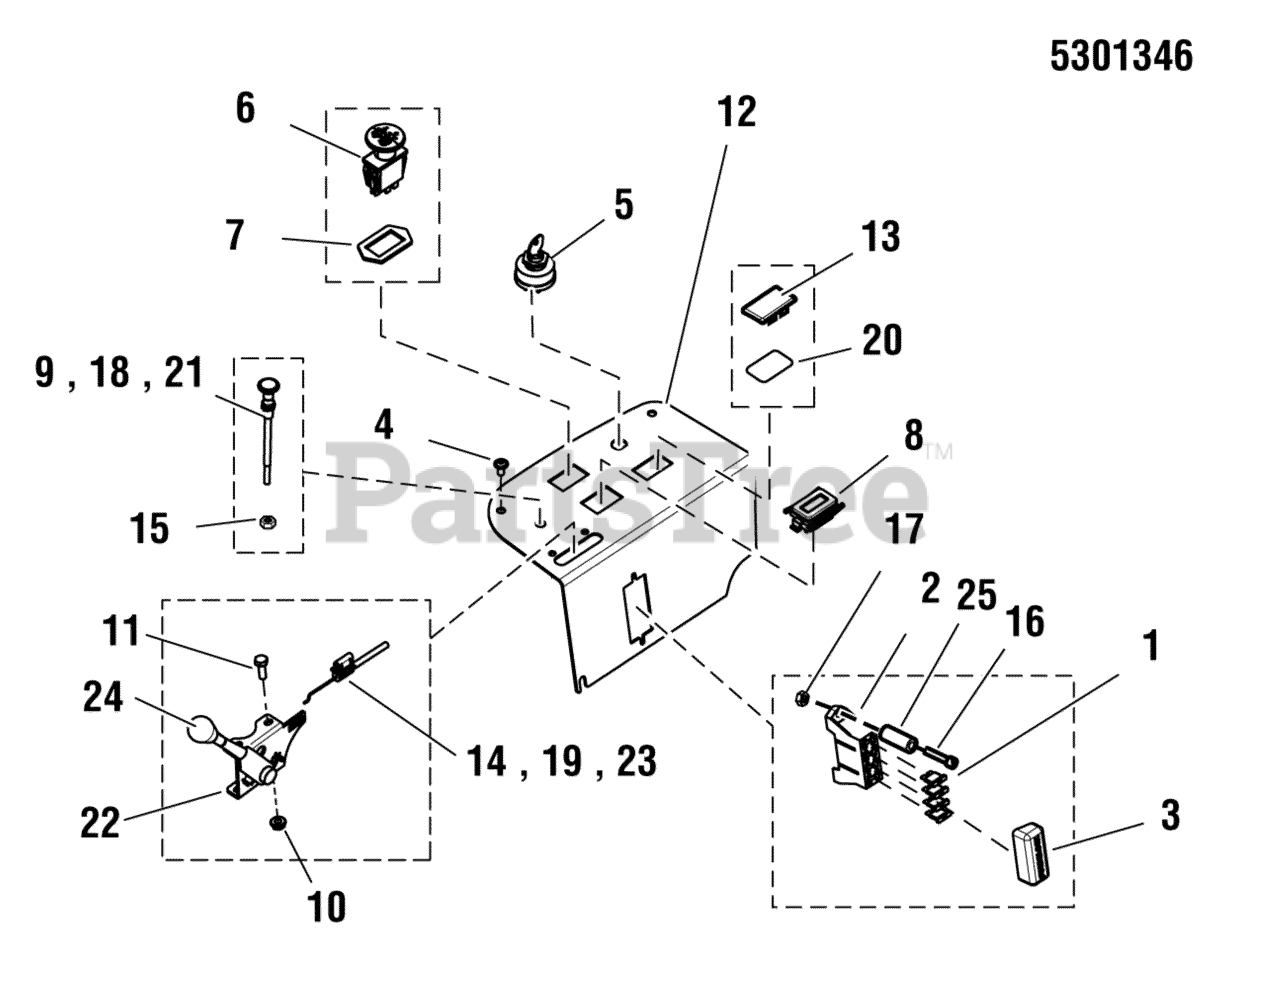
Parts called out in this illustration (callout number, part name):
1	FUSE, ATO-20 (20 AMP)(SV)
2	FUSE, BLOCK (SV)
3	COVER, VINYL, FUSE BLOCK
4	SCREW, ALLEN HEAD 1/4-20X.500 ZINC PHOS
5	SWITCH, IGNITION, 6 POST
6	SWITCH, BLADE ENGAGEMENT
7	RING, SWITCH RETAINER
8	HOUR METER, ASSEMBLE
8	HOUR METER
9	CABLE, Choke Control, 47"
10	NUT, Hex, Nylon Lock, #10-24
11	SCREW, #10-24 X 3/4" ROUND PHILLIPS
12	PANEL, CONTROL
12	PANEL, CONTROL, IS2000Z
13	PLUG, .820X1.44 HOLE, BLACK PLASTIC
14	CABLE, THROTTLE 47"
15	NUT, 3/8-24 HEX (SV)
16	SCREW, #10-24 X 2" ROUND PHILLIPS
17	NUT, Hex, Nylon Lock, #10-24
18	CABLE, CHOKE CONTROL, 56", DETENTED
19	CABLE, THROTTLE, 52"
20	O-RING, 7/8" ID X 1/16" W
21	CABLE, CHOKE CONTROL, 51" (Z)
22	LEVER, THROTTLE CONTROL, HEAVY-DUTY
23	CABLE, THROTTLE, 42"
24	THROTTLE CONTROL HANDLE/KNOB
25	SPACER, .20 X .38 X 1.25
